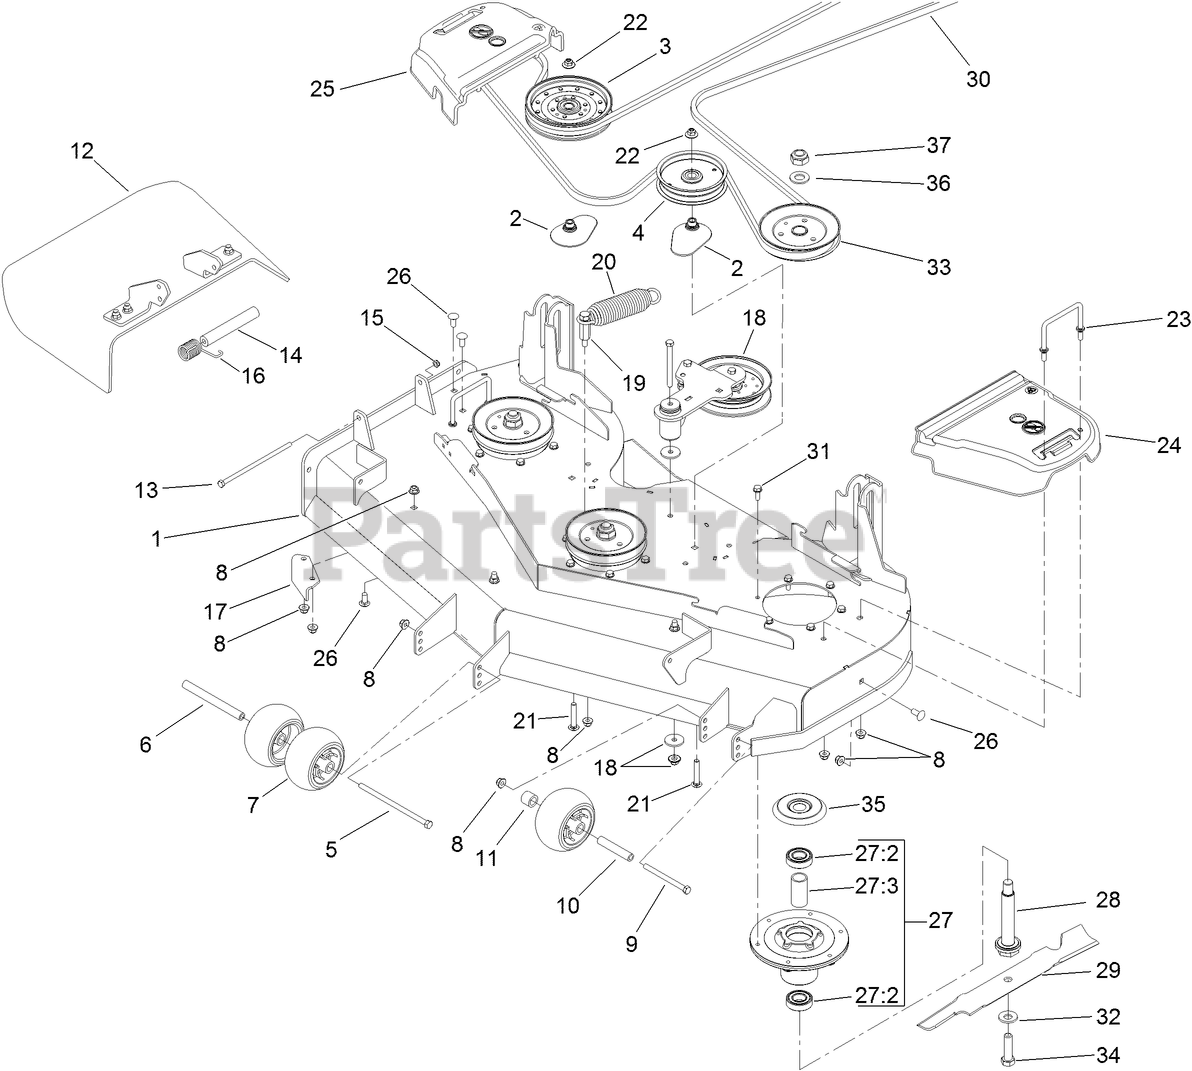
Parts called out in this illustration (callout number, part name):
1	DECK DECAL ASM
2	SPACER-PULLEY
3	PULLEY-IDLER, FLAT
4	PULLEY-IDLER
5	SCREW-HH
6	SPACER-WHEEL
7	ROLLER-SCALP, ANTI
8	NUT-HF, NI
9	SCREW-HH
10	TUBE-SPANNER
11	TUBE-SPACER
12	DEFLECTOR ASM
13	SCREW-HH
14	SPACER
15	NUT-LOCK, NI
16	SPRING-TORSION
17	BAFFLE-DISCHARGE
18	IDLER ARM ASM
19	ANCHOR-SPRING, TALL
20	EXTENSION-SPRING
21	BOLT-CARR, SHORT NECK
22	NUT-FLANGE, NI
23	WIREFORM-COVER
24	COVER-BELT, LH
25	COVER-BELT, RH
26	SCREW-CARR
27	SPINDLE ASM
27:2	BEARING-BALL
27:3	SPACER-BEARING
28	SPINDLE-SHAFT
29	BLADE-HI FLO, 16.50 INCH
30	BELT-V
31	SCREW-TAPTITE
32	WASHER-BELLEVILLE
33	PULLEY-B SECTION
34	SCREW-BLADE
35	SHIELD-BEARING
36	WASHER
37	NUT-LOCK, NI
